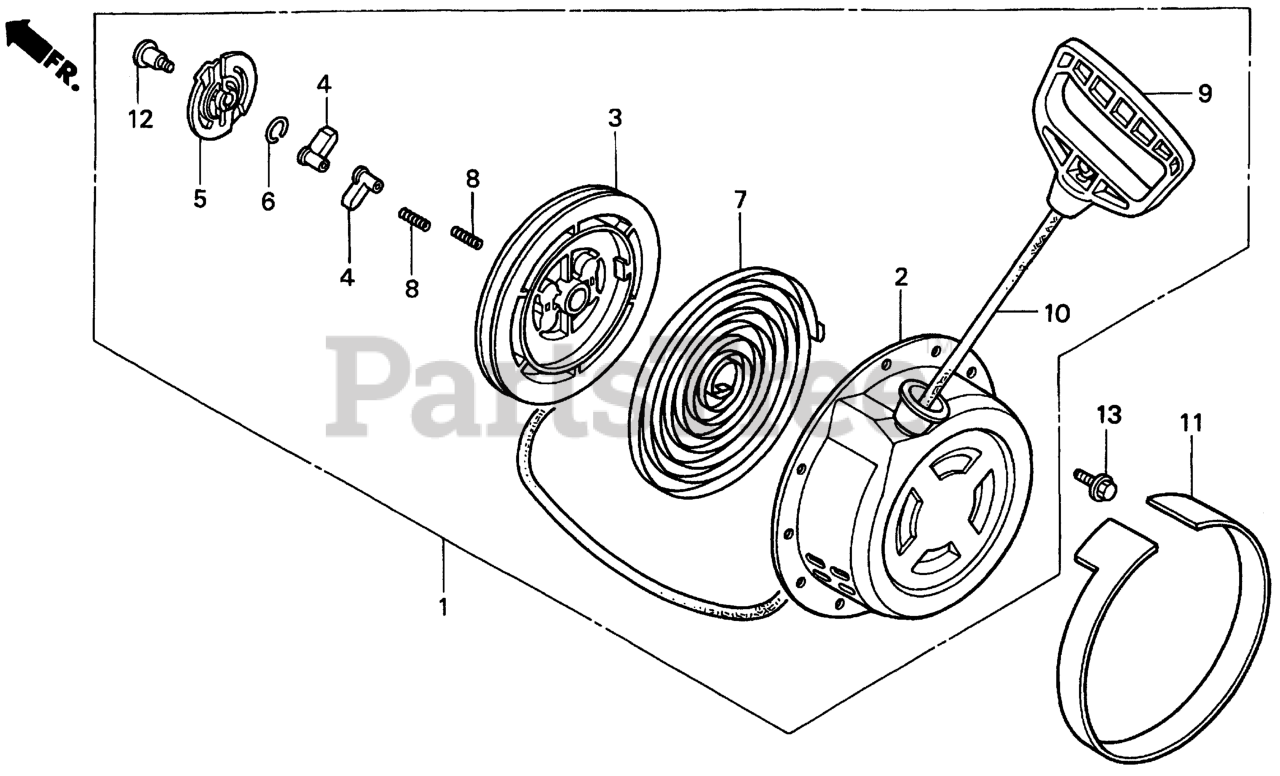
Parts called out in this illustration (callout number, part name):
1	STARTER ASSY., RECOIL *R280* (POWER RED)
2	CASE, RECOIL STARTER
3	REEL, RECOIL STARTER
4	RATCHET, STARTER
5	GUIDE, RATCHET
6	SPRING, FRICTION (ENGINE NO.)
7	SPRING, RECOIL STARTER
8	SPRING, RETURN (ENGINE NO.)
9	GRIP, STARTER
10	ROPE, RECOIL STARTER (#5X55") (NA USE ALT:08550-ZG921-11)
11	PLATE, RECOIL STARTER
12	SCREW, SETTING (ENGINE NO.)
13	BOLT, FLANGE (6X10)
